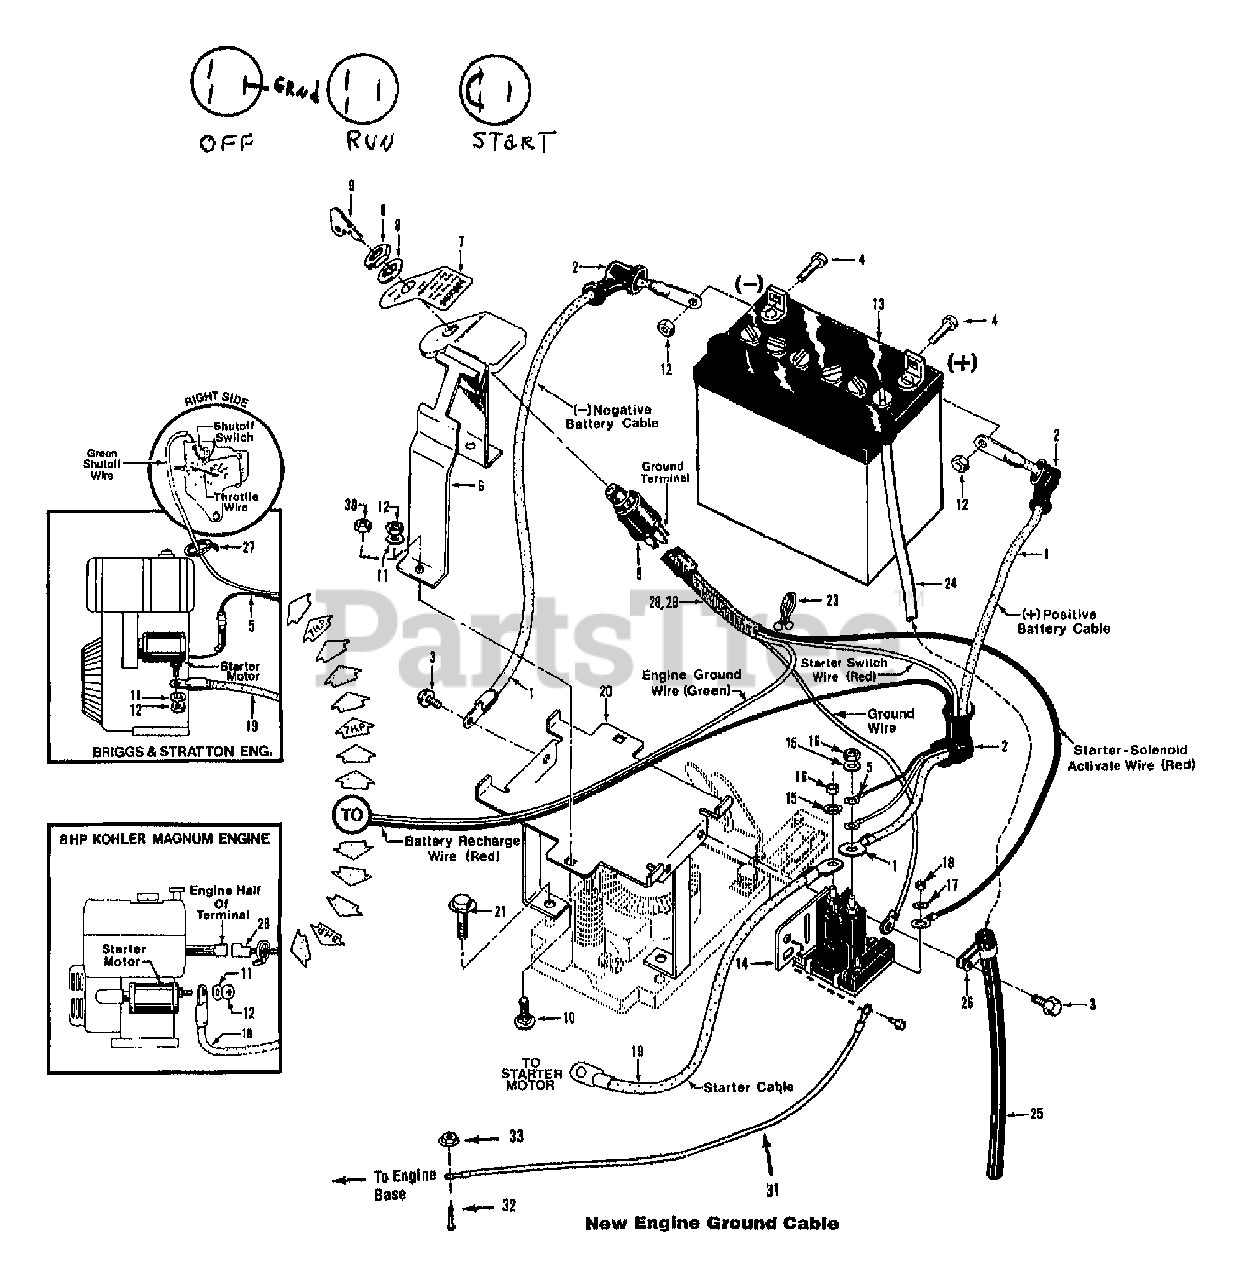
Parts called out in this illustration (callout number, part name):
1	CABLE-BATTERY 10"
2	BOOT-BATTERY CABLE
3	SCR-HWH 1/4-20 X .5 STH
4	SCR-HH 1/4-20X.625
5	WIRE-RECHARGE 5&7 BRIGGS (INCL. TERMINAL & EYELET)
6	CLAMP-KEYSWITCH W/DECAL OPC
7	DECAL-KEYSWITCH TILLER
8	ASSM-KEYSWITCH ELEC TLR
9	KEYS-IGN T/BLAZER 1 PAIR
10	SCR-CARR 1/4-20X1.25
11	WASHER-LK .25 ZP
12	NUT-HEX 1/4-20 ZP
13	BATTERY-12 VOLT HORSE (INCL. #9009 VENT TUBE)
14	SOLENOID (INCL. NUTS & WASHERS FOR CABLES & WIRES)
15	WASHER-LK .312 ZP
16	NUT-HEX 5/16-24
17	WASHER-EXTERNAL TOOTH 1
18	NUT-HH M10-32X.125
19	CABLE-BATTERY 12"
20	BRKT-BATTERY OPC PNT
21	SCR-HFLK 3/8-16X1.50
23	TIE-TWIST LOCK
24	TUBE-VENT BATTERY/HSE
25	TUBING-RUBBER
26	CLAMP
27	TIE-RED
28	KIT-WIRE HARNESS ASSM
29	ASSM-WIRE HARNESS
30	NUT-HF/LK 1/4-20 ZP
31	CABLE-BATTERY 15"
32	SCR-HFLK 5/16-18X1.00 ZP (FOR KOHLER ENGINE ONLY)
33	NUT-HFLK 5/16-18 ZP (FOR KOHLER ENGINE ONLY)
